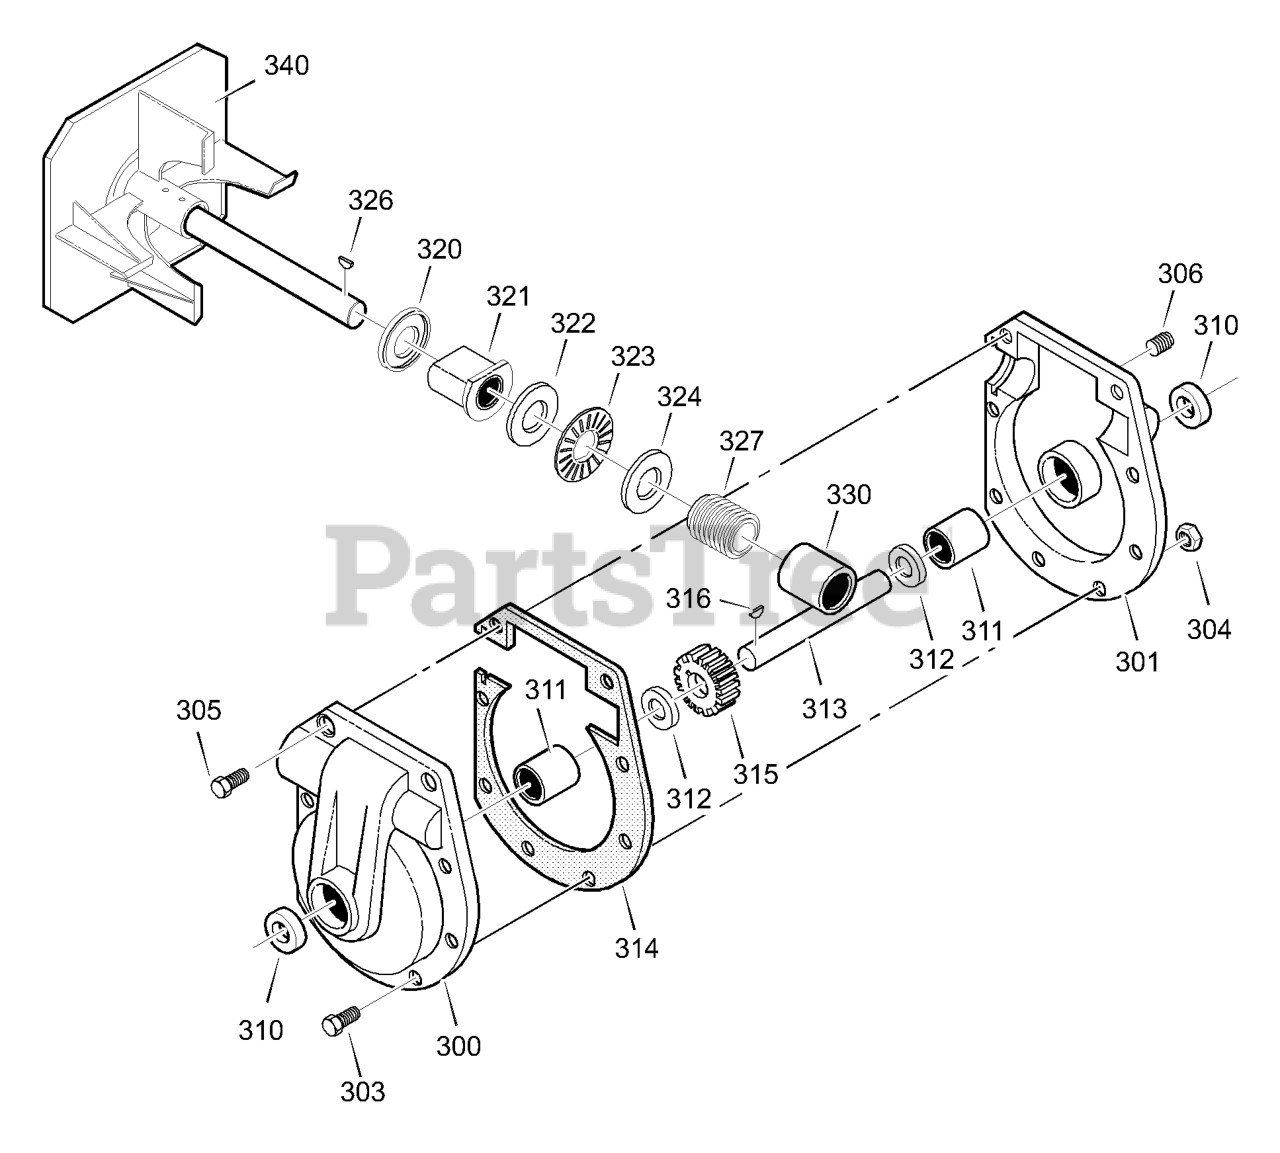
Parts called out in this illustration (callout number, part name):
300	CASE, GEAR, RH
301	CASE, GEAR, LH
303	SCREW, 5/16-24 x 1.00
304	NUT, 5/16-24
305	SCREW, 5/16-24 x 1.50
306	PLUG, PIPE 0.25-18
310	SEAL, OIL
311	BEARING, SLEEVE
312	WASHER, FLAT
313	SHAFT, AUGER OUTPUT
314	GASKET, GEAR BOX
315	WORM GEAR
316	KEY, WOODRUFF #91
320	RING, QUAD 0.924 ID
321	BEARING, FLANGE
322	WASHER, FLAT
323	BEARING, ROLLER
324	WASHER, FLAT
330	BEARING, SLEEVE
340	IMPELLER
